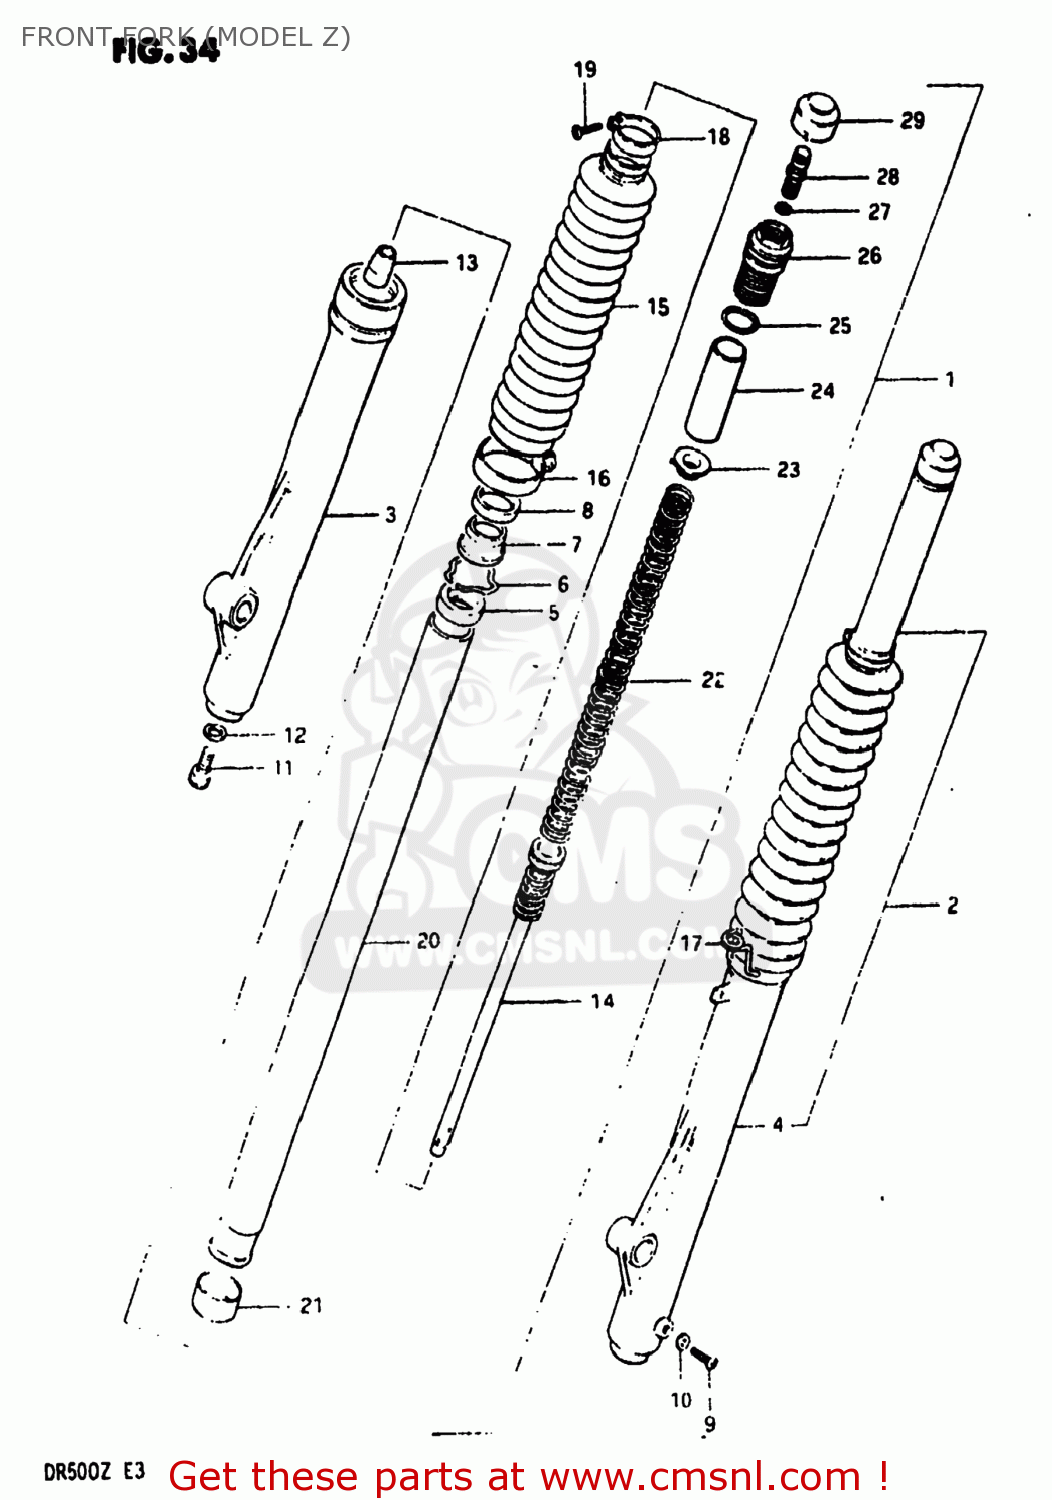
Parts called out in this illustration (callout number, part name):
1	DAMPER ASSEMBLY,RIGHT
2	DAMPER ASSEMBLY,LEFT
3	TUBE,OUTER,RIGHT
4	TUBE,OUTER,LEFT
5	OIL SEAL,FRONT FORK
6	7
7	SEAL,DUST
8	CASE,DUST SEAL
9	SCREW
10	GASKET,DRAIN,PLUG (NAS)
11	BOLT,FORK CYLINDER(10X25)
12	GASKET (NAS)
13	PIECE,OIL LOCK
14	CYLINDER,FRONT FORK
15	BOOT
16	BAND,FRONT FORK COVER
17	BAND,FRONT FORK COVER
18	BAND,BOOT
19	SCREW
20	TUBE,FORK,INNER
21	PISTON
22	SPRING,FRONT FORK
23	GUIDE,FRONT FORK SPRING C
24	COLLAR,SPRING
25	O RING
26	CAP,FORK INNER TUBE
27	O-RING
28	VALVE,FRONT FORK AIR
29	CAP
